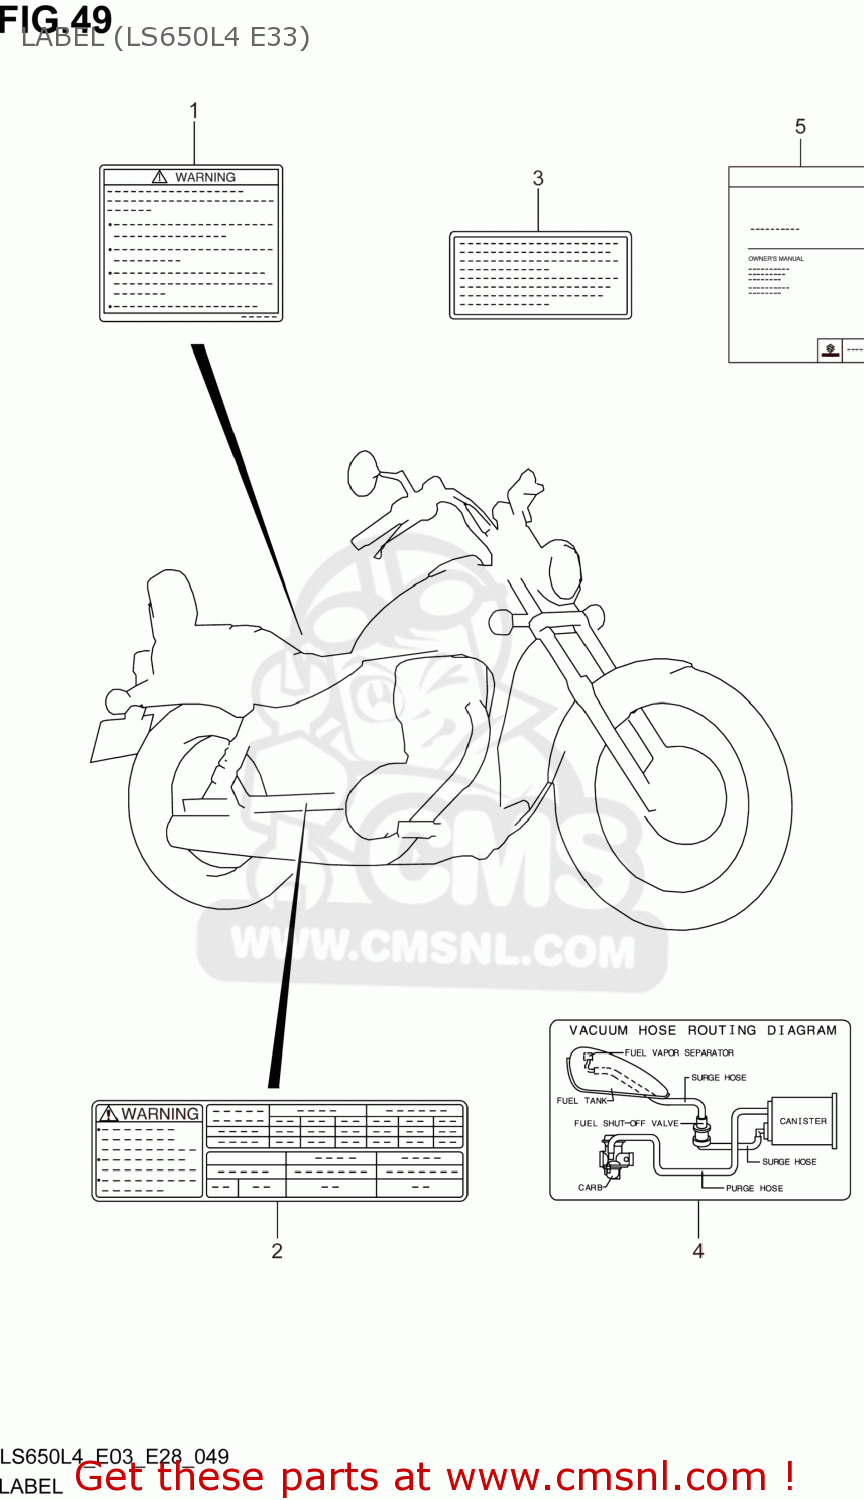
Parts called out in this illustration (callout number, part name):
1	LABEL,GENERAL WARNING
2	LABEL,TIRE INFORMATION
3	LABEL,MANUAL NOTICE
4	LABEL,VACUUM HOSE ROUTING
5	MANUAL,OWNER'S
